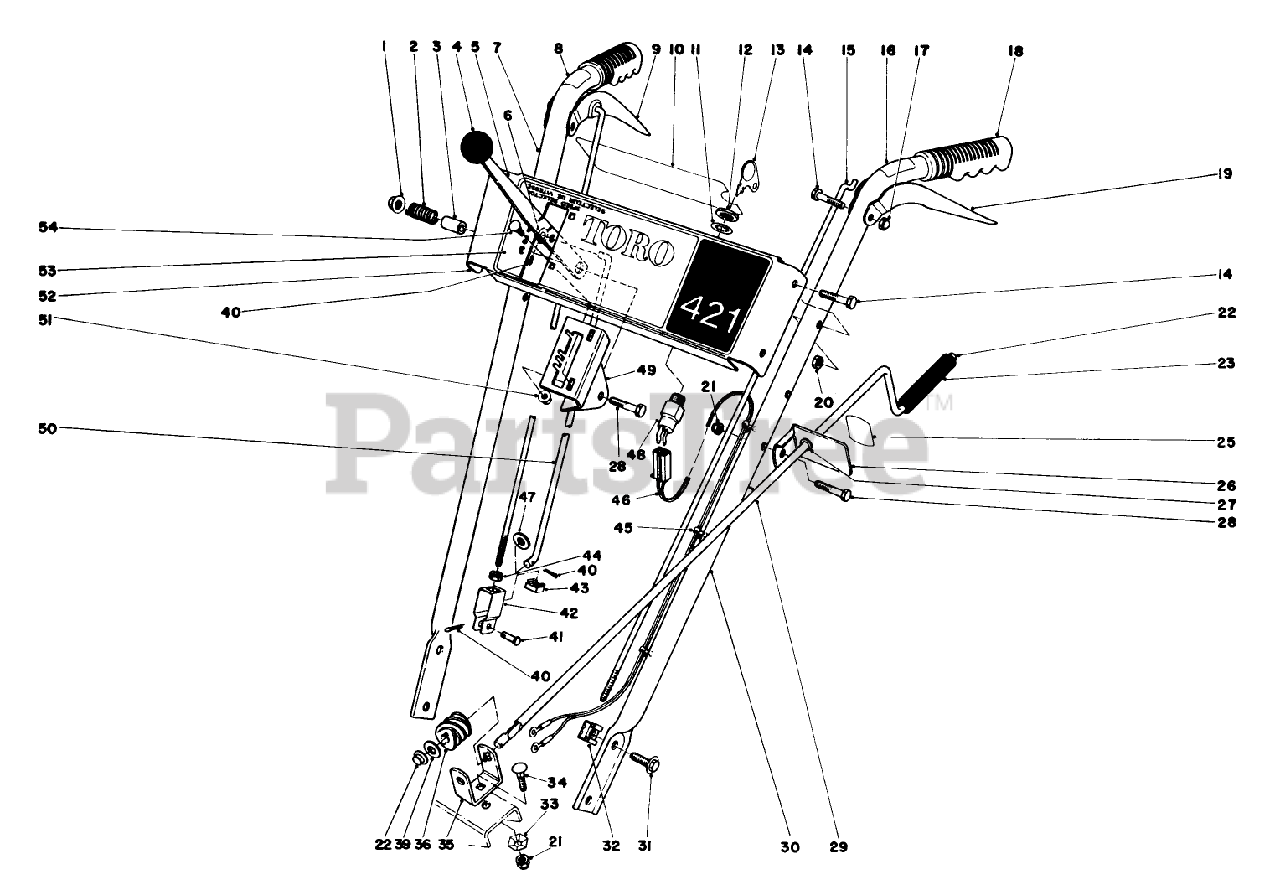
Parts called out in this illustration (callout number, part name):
1	NUT-HF
2	SPRING
3	SPACER
6	WASHER-FLAT
11	WASHER-LOCK
12	NUT-HH
14	SCREW-HH
17	NUT-CAP
20	NUT-LOCK, CONE
21	NUT-LOCK, NI
22	NUT-PUSH
23	GRIP-CONTROL, CHUTE
28	SCREW-HH
29	ROD-CONTROL, CHUTE
31	SCREW-HHF
33	WASHER-LOCK
34	BOLT-CARR
35	BRACKET-WORM
36	GEAR-WORM, CHUTE
39	WASHER-FLAT
40	PIN-COTTER
41	PIN-CLEVIS
42	CLEVIS
43	NUT-RETAINED
44	NUT-JAM
45	TIE-CABLE
46	WIRE HARNESS
47	WASHER-PLAIN
50	ROD-SELECTOR, SPEED
51	NUT-HHF
